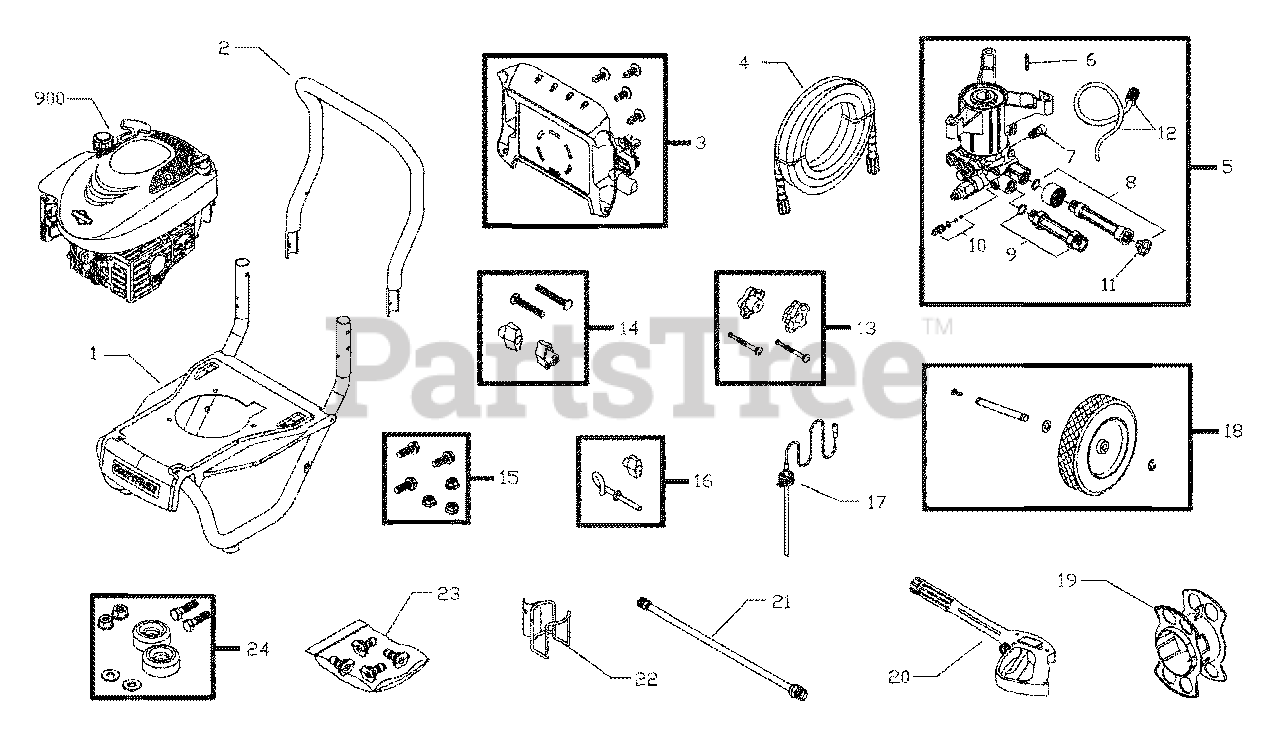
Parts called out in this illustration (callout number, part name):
1	BASE, w/Vib Mounts
2	HANDLE
3	KIT, Billboard w/Clips & Decals
4	HOSE
5	PUMP, Complete
7	Valve, Thermal Relief
8	Kit, Water Inlet
9	Kit, Water Outlet
12	Kit, Chemical Hose
15	KIT, Pump Mounting Hardware
16	KIT, Rope Guide
20	GUN
21	EXTENSION, QC
23	KIT, Spray Tips
24	KIT, Vibration Mount
